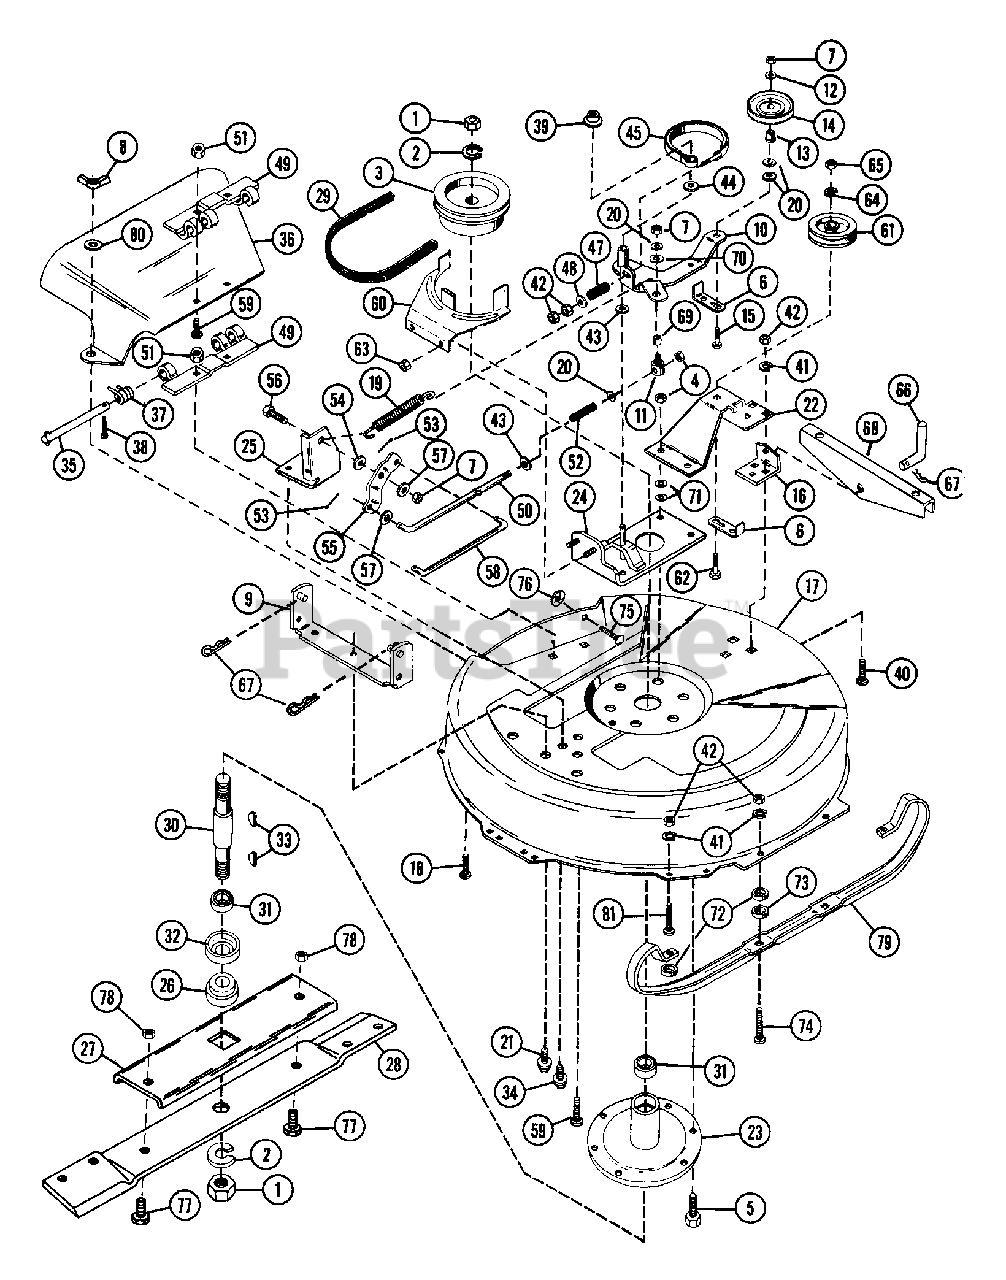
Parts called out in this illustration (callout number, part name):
1	NUT-JAM .75-10 PL
2	WSHR-LK .750X.188 MED PL
3	MOWER SHEAVE
4	NUT-LK-CTR .375-16 GR A PL
5	BLT-HEX .38-16X1.00 PL
6	BELT FINGER
7	NUT-LK .312-18 GR A PL
8	NUT-WING W/INSERT .312 - 18
9	FRONT MOUNTING BRACKET
10	IDLER ARM
11	ROD PIVOT
12	WSHR-FL-STL .323X.625X.062 PL
13	SPCR, BRG .315X.50X.688X.281
14	IDLER
15	BLT-HEX .31-18X1.50 PL GR2
16	REAR MOUNTING BRACKET
17	32 IN MOWER PAN SERVICE ASSEMB
18	BLT-RDHDSQNK .31-18X1.00 PL
19	SG-TENS .072X.51X5.31 WLD 25
20	WSHR-FL-STL .38X.875X.083 PL
21	BLT-SCRHFWH .38-16X.50 PL
22	IDLER MOUNT
23	SPINDLE HOUSING
24	PIVOT PLATE
25	DECK PIVOT BRACKET
26	RETAINER HUB
27	BLADE TRAY
28	MOWER BLADE 32
30	SPINDLE SHAFT
31	BRG-BALL .750X1.781X.61
32	BEARING SLINGER
33	KEY-WDRF .188X.75X.313 SAE 9
34	BLT-SERHFWH .31-18X.50 PL
35	CLEVIS PIN
36	CHUTE DEFLECTOR
37	SG-TORS .090X.37X.63
38	PIN-COTR .09X.75 PL
39	FASTENER
40	BLT-RDHDSQNK .31-18X.75 GR5 PL
41	WSHR-LK .312X.097 PL HVY
42	NUT-HEX .312-18
44	WSHR-FL-STL .531X1.062X.095 PL
45	BRAKE BAND
46	PIN-COTR .06X.50
47	SG-COMP .072X.687X.75
48	WSHR-FL-STL.344X.688X.065PL
49	HINGE PLATE
50	CLUTCH ROD
51	NUT-LK-CTR .250-20 PL
52	SG-COMP .148X.68X6.5 WLD 90
53	PIN-COTR .12X.75 PL
54	SPACER BUSHING .5 X .32 X .163
56	BLT-HEX .31-18X.88 PL GR2
57	WSHR-FL-STL .344X1.125X.063PL
58	CLUTCH ROD
59	BLT-RDHDSQNK .25-20X.62 PL
60	BELT FINGER
61	IDLER-V 3.06 X .38
62	BLT-HEX .38-16X1.75 PL GR2
63	NUT-FLG. .312-18 PL
64	WSHR-LK .375X.094 MED PL
65	NUT-HEX .375-16
66	CLEVIS PIN
67	PIN-HAIR INT .08X.38X1.42 YWZC
68	SWIVEL BRACKET
69	SPACER BUSHING .5 X .32 X .21
70	WAVE WASHER .531X.781X.125FH
71	WSHR-FL-STL .438X1.0X.083 PL
72	SPACER .328X.750X.375
73	SPACER BUSHING .5 X .32 X .21
74	BLT-RDHDSQNK .31-18X1.75 SHTPL
75	BLT-RDHDSQNK .312-18X.62SHTPL
76	NUT-PUSH .312
77	BLT-HEX .38-16X.75 PL GR5
78	NUT-LK TOP .375-16 GR C YWZC
79	32 IN ADJUSTABLE SKID
80	WSHR-FL-STL .328X.875X.062 PL
81	BLT-RDHDSQNK .31-18X1.25 SHTPL
